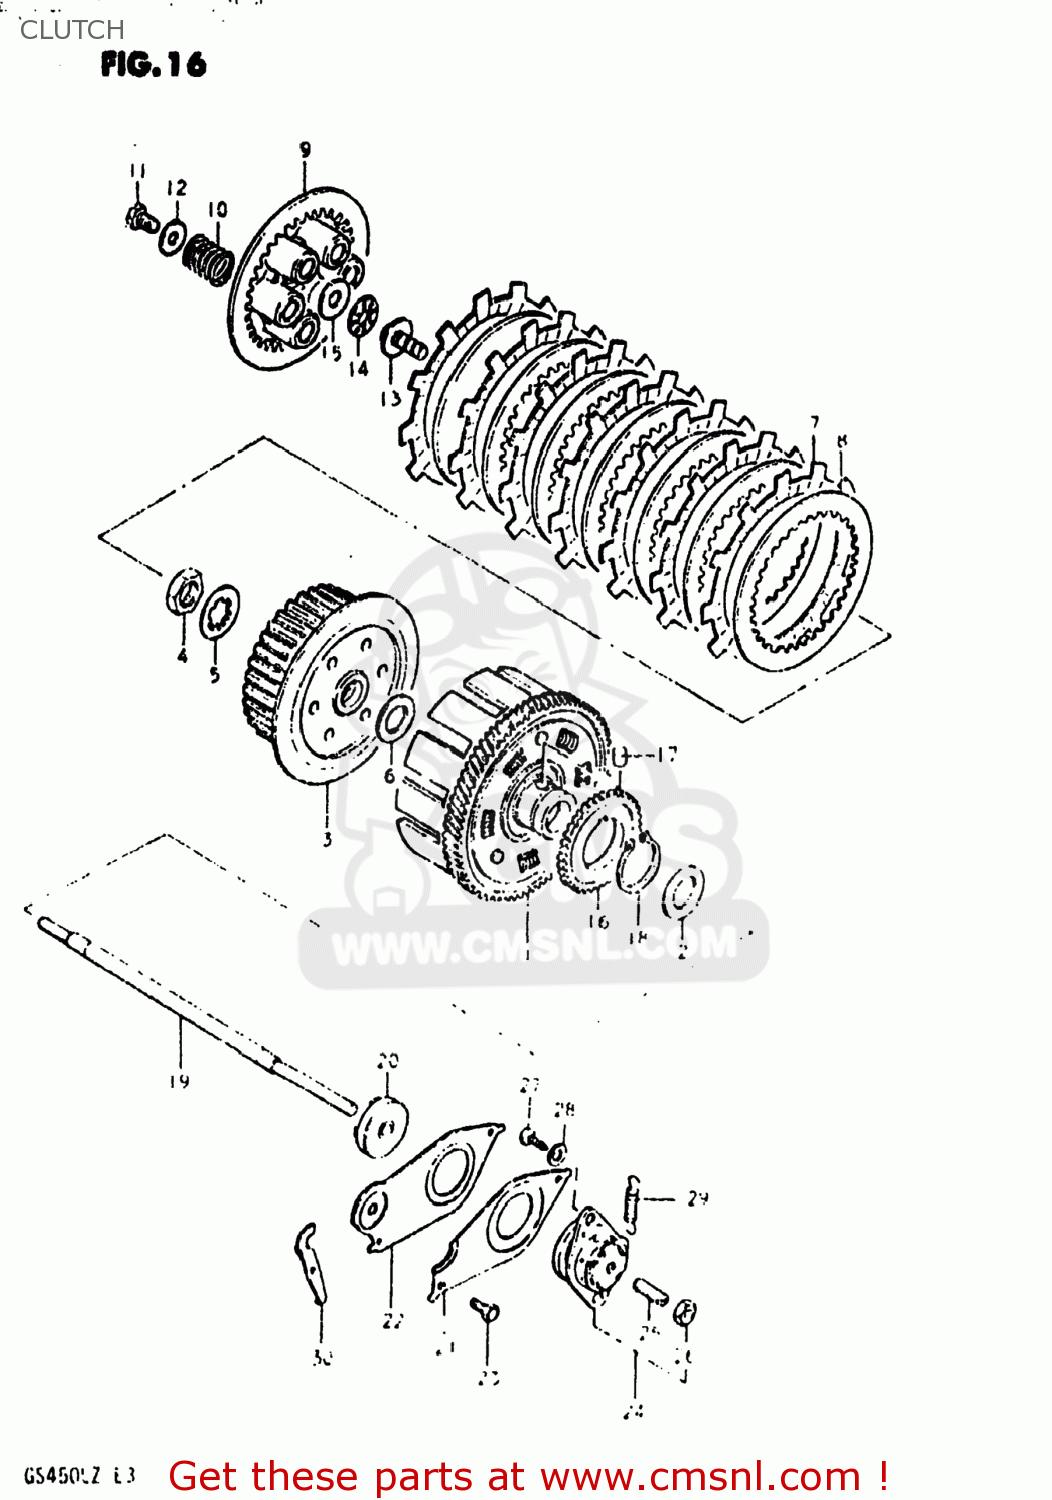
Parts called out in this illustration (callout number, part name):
1	GEAR ASSEMBLY,PRIMARY DRIVE
2	WASHER
3	HUB,CLUTCH SLEEVE
4	NUT (20MM)
5	WASHER,LOCK
6	WASHER(20X44X3)
7	PLATE,CLUTCH DRIVE (MCA)
8	PLATE,CLUTCH DRIVEN (NAS)
9	DISC,CLUTCH PRESSURE
10	SPRING
11	BOLT, UPPER
12	WASHER
13	PIECE,CLUTCH PUSH
14	BEARING(15X28X2)
15	WASHER
16	GEAR,OIL PUMP DRIVE
17	PIN(6X6)
18	CIRCLIP
19	ROD,CLUTCH PUSH
20	SEAL,OIL(6X34X8)
21	PLATE,CLUTCH PUSH ROD
22	PLATE,CLUTCH PUSH ROD
23	BOLT
24	SCREW ASSEMBLY,CLUTCH RELEASE
25	SCREW
26	NUT 6MM
27	SCREW
28	WASHER
29	SPRING
30	GUIDE,PUSH ROD OIL SEAL
